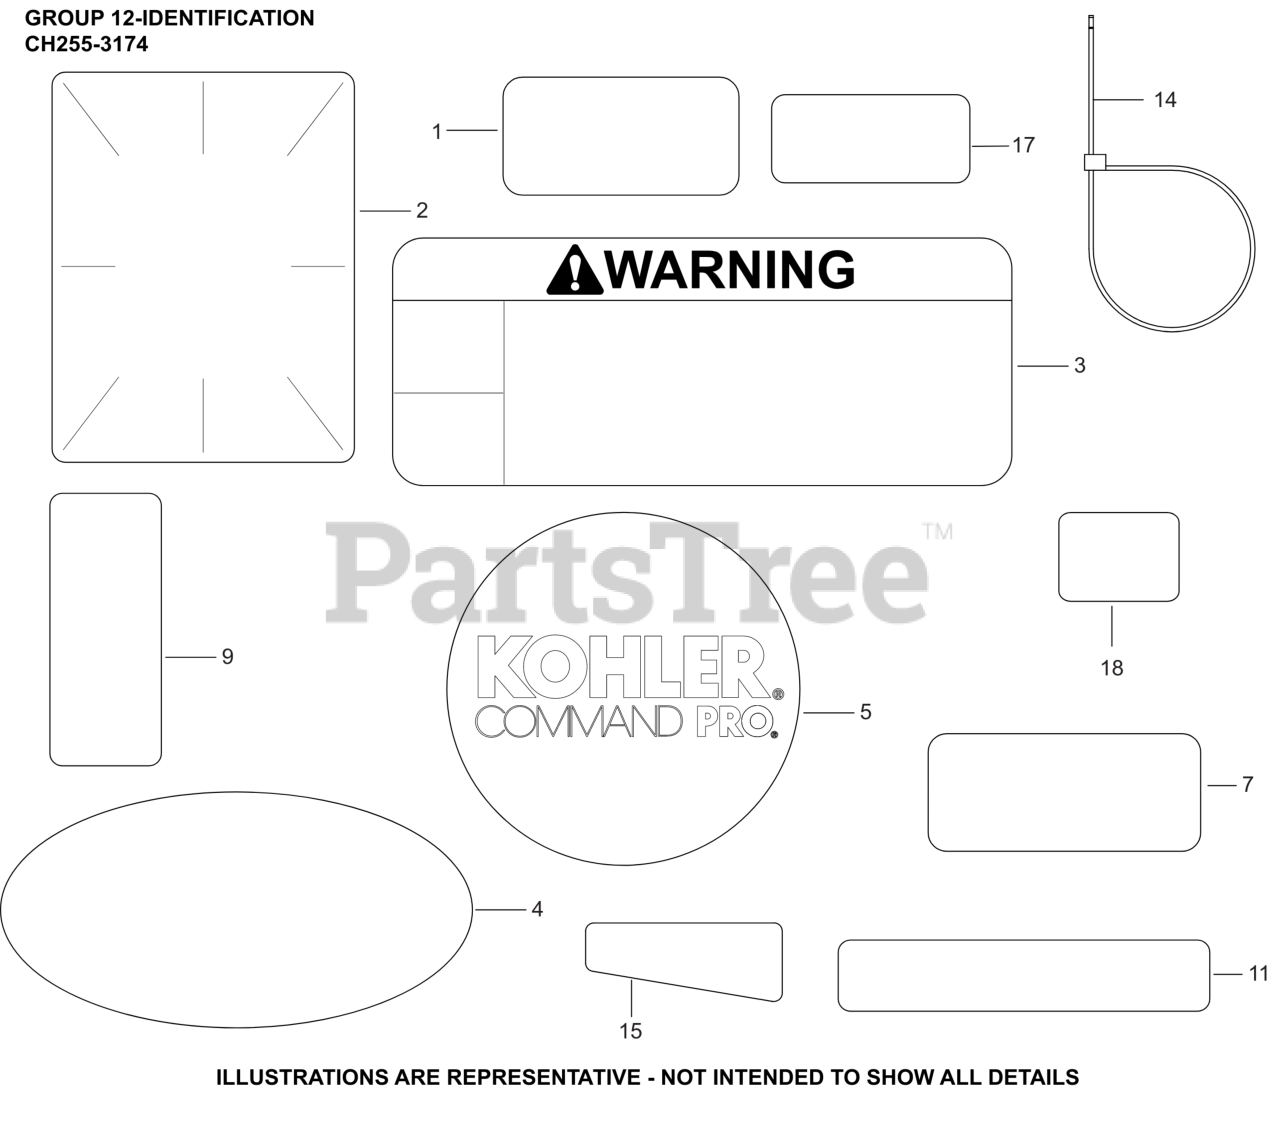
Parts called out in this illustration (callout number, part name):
1	LABEL, MAINTENANCE (CKY)
2	LABEL, CLEAR LAMINATION
3	DECAL, WARNING
4	DECAL, QUAD CLEAN
5	LABEL, RECOIL 75MM
7	LABEL, CANADIAN COMPLIANCE
9	DECAL, FUEL/CHOKE - ON/OFF
11	LABEL, THROTTLE
15	DECAL, 5.5HP/177CC CH255
17	DECAL, ETHANOL WARNING
18	DECAL, SUN
18	DECAL, SNOW
18	DECAL, ARROW
